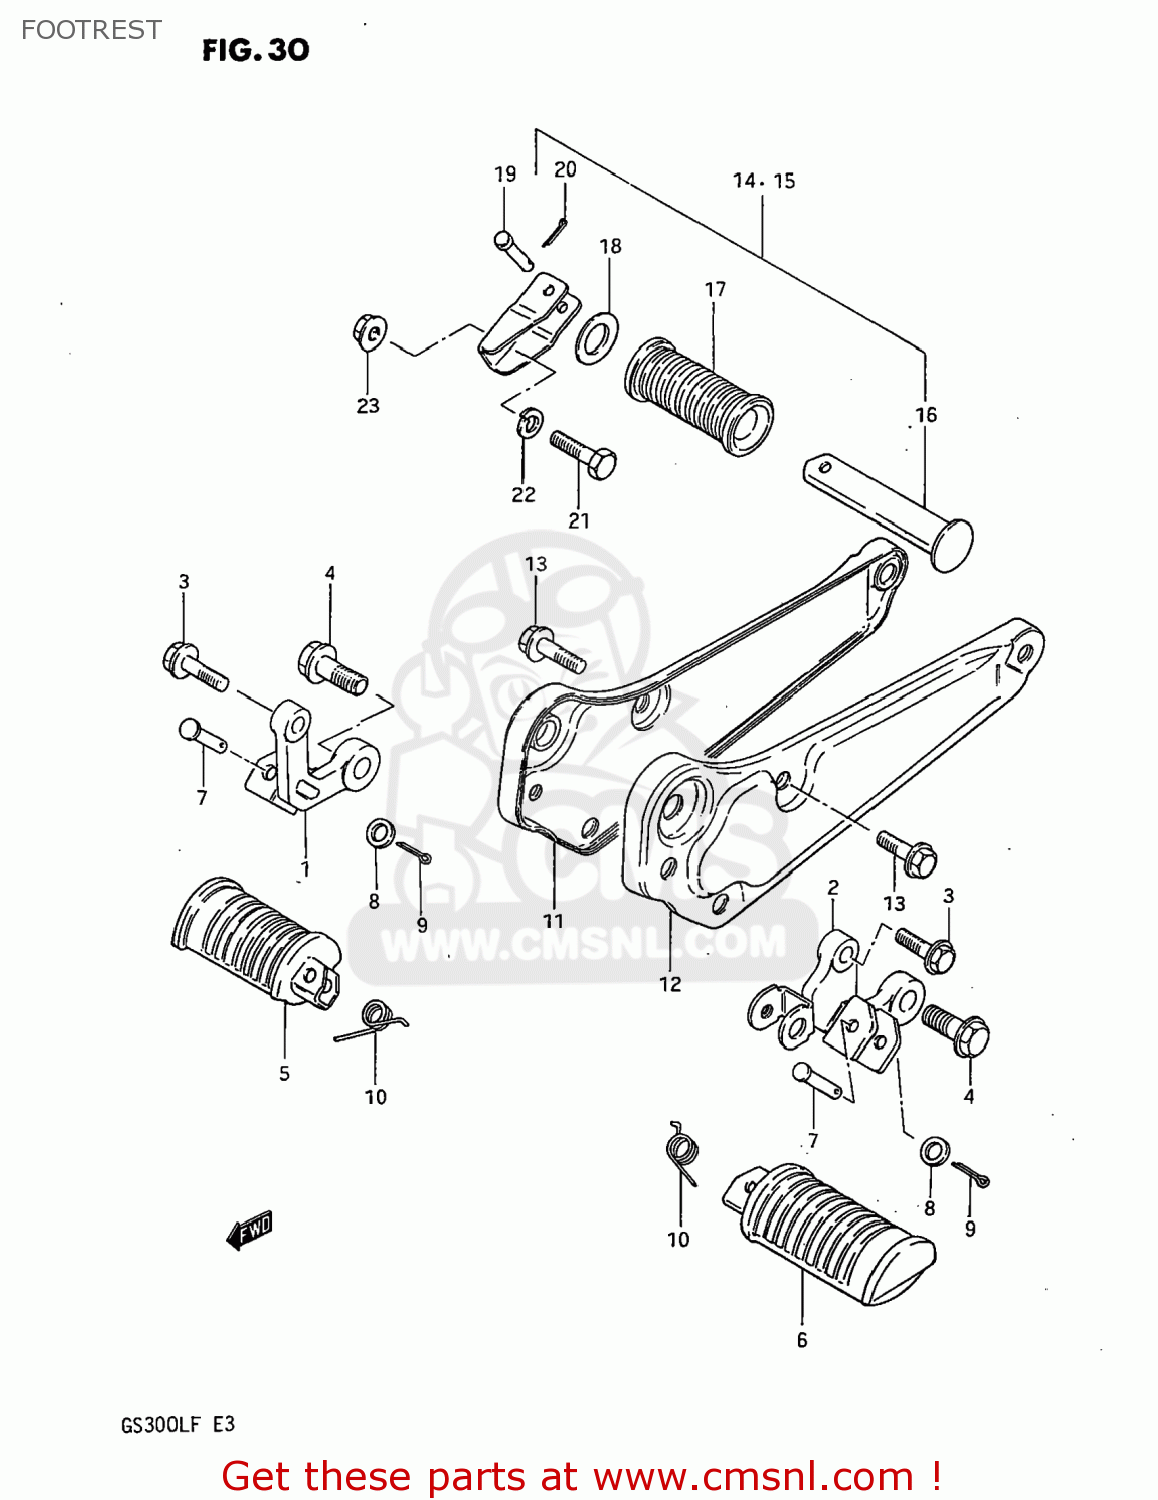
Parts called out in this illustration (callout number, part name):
1	BAR,FRONT FOOTREST
2	BAR,FRONT FOOTREST,LEFT
3	BOLT 8X30
4	BOLT
5	RUBBER,FRONT FOOTREST
6	FOOTREST
7	PIN
8	WASHER
9	PIN 20X20
10	SPRING
11	BRACKET,MUFFLER,RIGHT
12	BRACKET,MUFFLER,LEFT
13	BOLT
14	FOOTREST ASSEMBLY,PILLION
15	FOOTREST ASSEMBLY,LEFT
16	BAR,PILLION FOOTREST
17	RUBBER,PILLION FOOTREST
18	WASHER (19.5X32X2)
19	PIN
20	PIN 20X20
21	BOLT,M10X1.25X
22	LOCK WASHER
23	NUT
